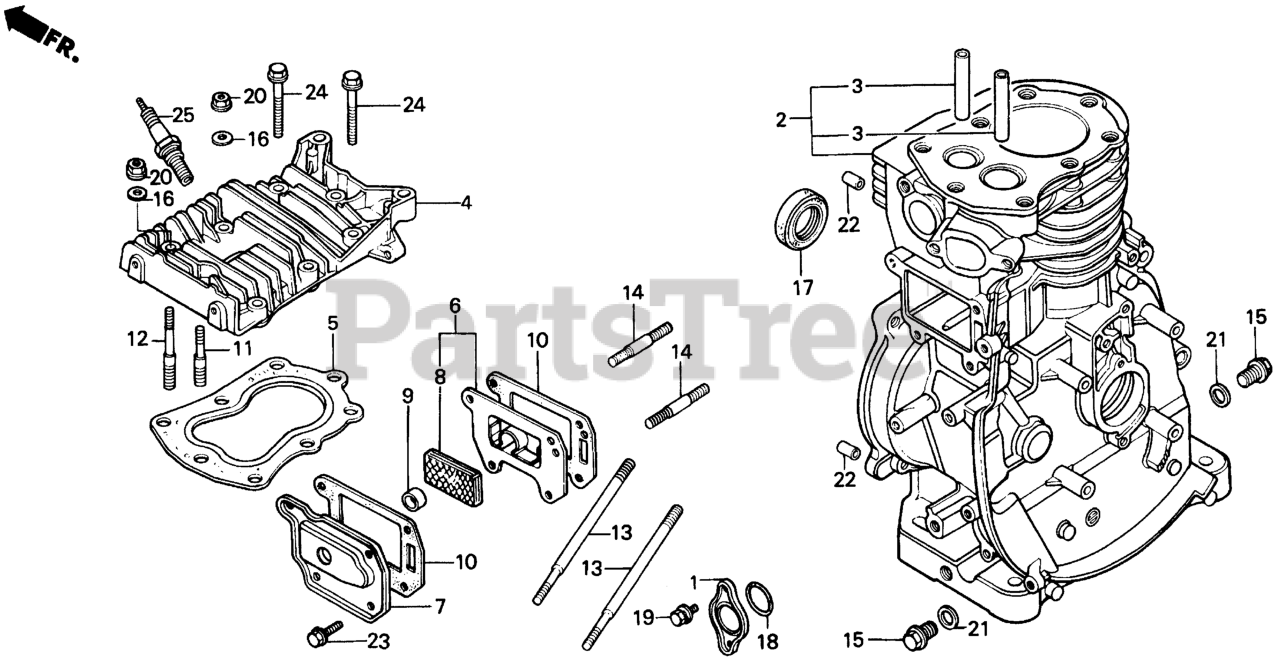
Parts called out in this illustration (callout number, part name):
1	COVER, OIL PAN
2	CYLINDER
3	GUIDE, VALVE
4	CYLINDER HEAD
5	GASKET, CYLINDER HEAD
6	CASE, BREATHER
7	COVER, TAPPET
8	FILTER, BREATHER
9	SEAL, BREATHER
10	GASKET, TAPPET COVER Use up to Engine SN 1136497.
11	BOLT, STUD (M8XM10X63)
12	BOLT, STUD (M8XM10X81)
13	BOLT, STUD (8X110)
14	BOLT, STUD (8X35)
15	BOLT, DRAIN PLUG
16	WASHER (8MM)
17	OIL SEAL (25X41X6)
18	O-RING (27X2.0)
19	BOLT-WASHER (6X12)
20	NUT-WASHER (8MM)
21	WASHER, DRAIN PLUG (12MM)
22	PIN A, DOWEL (8X14)
23	BOLT, FLANGE (6X12) Use from Engine SN 2086984.
24	BOLT, FLANGE (8X50) (NOT AVAILABLE)
25	SPARK PLUG (BR-4HS) (NGK)
25	SPARK PLUG (W14FR-U) (DENSO)
